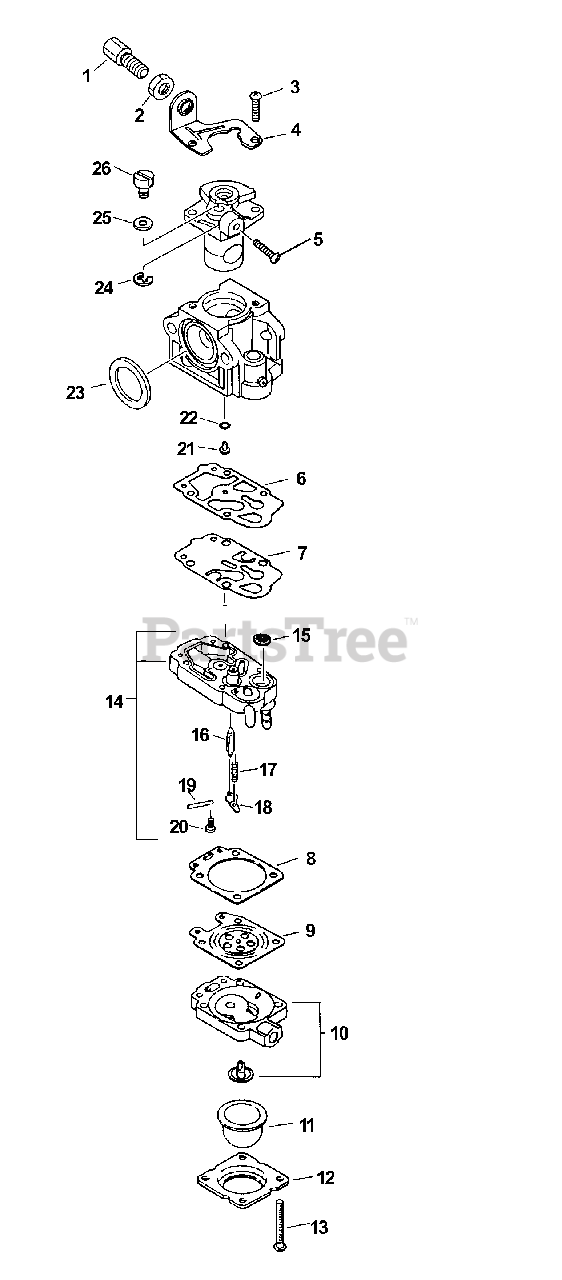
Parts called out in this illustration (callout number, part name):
1	NUT, CABLE ADJUST
4	BRACKET, THROTTLE CABLE
5	SCREW, IDLE ADJUST
6	GASKET, PUMP
7	DIAPHRAGM, PUMP
8	GASKET, METERING
9	DIAPHRAGM, METERING
10	PURGE BASE ASSY
11	BULB, PURGE
12	RETAINER, PURGE BULB
13	SCREW, PUMP COVER
14	BASE, PURGE
15	STRAINER
16	VALVE, INLET NEEDLE
17	SPRING, METERING LEVER
18	LEVER, METERING
19	PIN, METERING LEVER
20	SCREW, METERING LEVER PIN
21	JET, MAIN
23	SEAL
24	RING, RETAINING
